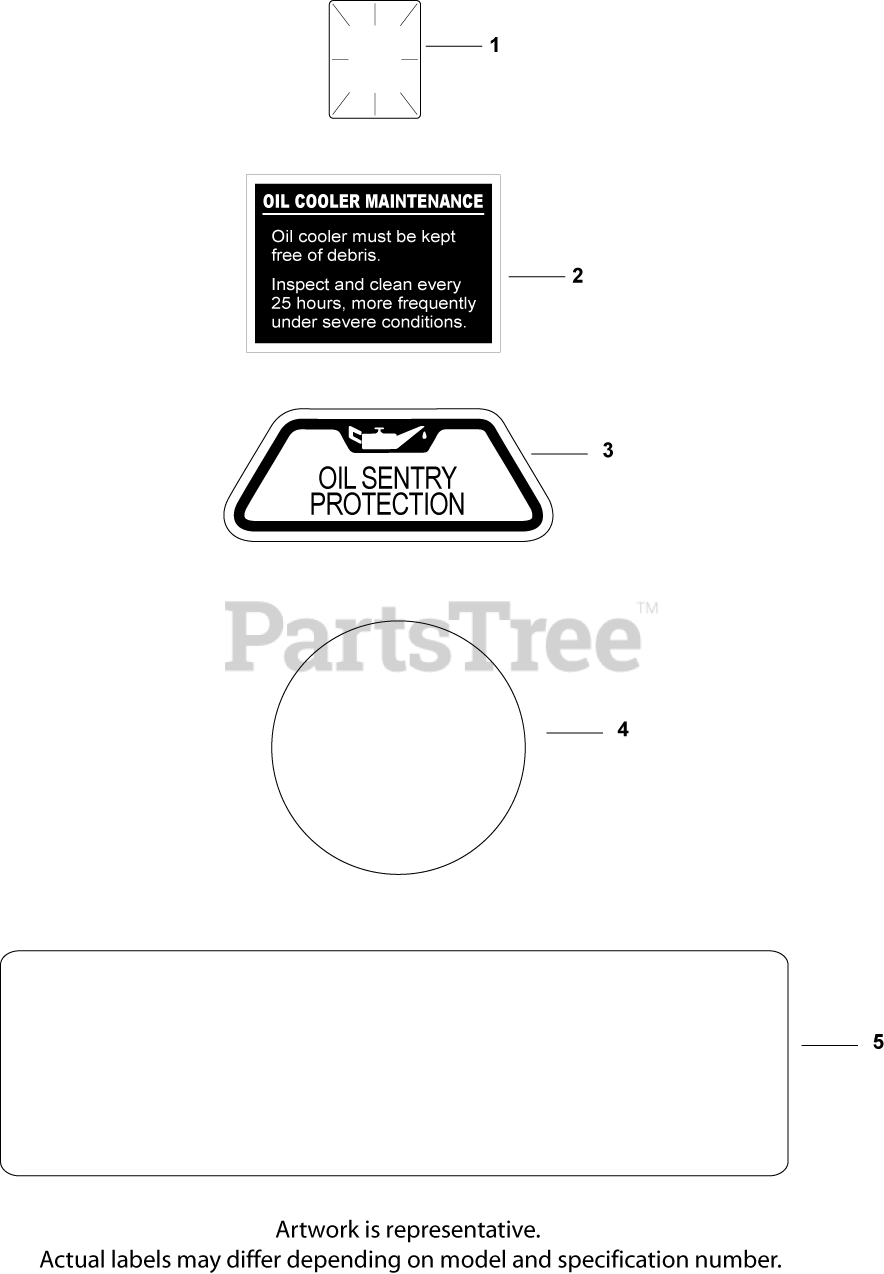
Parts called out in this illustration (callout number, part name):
1	DECAL, CLEAR LAMINATE USE 25 113 70-S
2	DECAL, OIL COOLER - (#DSC)
3	DECAL, OIL SENTRY - (#DSC)
4	DECAL, GRASS SCREEN USE 24 113 499-S
5	DECAL, 25 HP - DISCONTINUED
